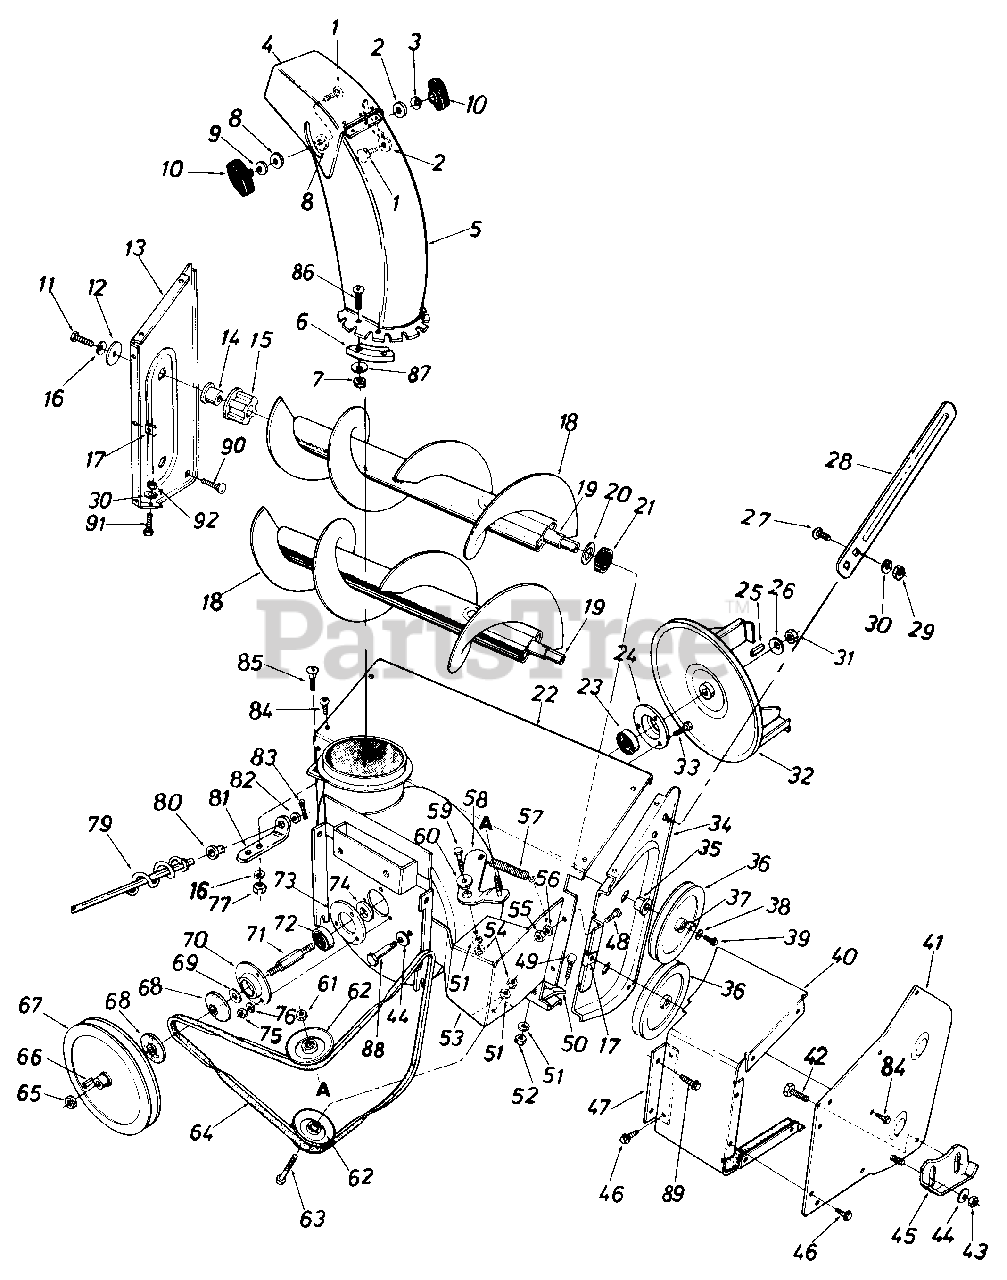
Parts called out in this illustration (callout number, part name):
1	Carriage Bolt 5/16-18 x 1.0" Lg.
2	Fl-Wash. .344" I.D. x 1.125 O.D.
3	Bell-Wash. .345" I.D. x .88" O.D.
4	Upper Chute
5	Lower Chute
6	Chute Flange Keeper
7	Hex Patch L-Nut 1/4-20 Thd.
8	Fl-Wash. .531' I.D. x 1.25" O.D.
9	Bell-Wash. .345" I.D. x .88" O.D.
10	Knob Handle Ass'y.
11	Hex Bolt 5/16-18 x 1.0" Lg. (Grade 5)
12	Fl-Wash. .32" I.D.
13	Spiral Housing Plate L.H.
14	Shaft Pin 1.0" O.D. x .94
15	Tubing Support Brg.
16	Bell-Wash. .345" I.D. x .88" O.D.
17	Speed Clip 1/4-20
18	Auger Ass'y. 22" x 6" Dia.
20	Fl-Wash. .760" I.D. x 1.75 O.D.
21	Spacer 1.25" I.D. x 1.50" O.D. x .58" Thk.
22	22" Spiral Housing Ass'y.
23	Ball-Brg. .787" I.D. x 1.85" O.D. x .551
24	Bearing Housing 1.85" I.D.
25	Sq. Key 3/16 x 1.50" Lg.
26	Bell-Wash. .630" I.D. x 1.25 O.D.
27	Carriage Bolt 5/16-18 x .62" Lg.
29	Hex Nut 5/16-18 Thd.
30	L-Wash. 5/16" I.D.
31	Hex Jam Nut 5/8-18 Thd.
32	11" Dia. Blower Fan Ass'y.
33	Hex Bolt 5/16-18 x 1.00" Lg. (Grade 5)
34	Spiral Housing Plate R.H.
35	Hex Flange Brg. .751 " I.D.
36	3/8" V-Pulley 5/8" I.D. x 5.5" O.D.
37	Sq. Key 3/16" X .75" Lg.
38	Bell-Wash. .265" I.D. x .75" O.D.
39	Hex Bolt 1/4-20 x .62" Lg.
40	Belt Cover Top
41	Belt Cover Side Ass'y.
42	Hex Bolt 3/8-16 x .75" Lg.
43	Hex Jam Nut 3/8-16 Thd.
44	Bell-Wash. .400" I.D. x .88" O.D.
47	Support Bracket
48	Hex Bolt 5/16-18 X .50" Lg.
49	Carriage Bolt 5/16-18 X .62" Lg.
50	Scraper Bar Kit 22"
51	Bell-Wash. .345" I.D. x .88" O.D.
52	Hex Nut 5/16-18 Thd.
54	Hex Nut 3/8-24 Thd.
55	Hex Nut 5/16-18 Thd.
56	L-Wash. 5/16" I.D.
57	Extension Spring .620" O.D. x 3" Lg.
58	Idler Bracket Ass'y.
59	Hex Bolt 3/8-24 x .75" Lg.
60	Shld. Spacer .625" I.D.
61	Hex Ins. L-Nut 3/8-24 Thd.
62	"V"-Idler 2.62" O.D.
63	Hex Bolt 3/8-24 x 1.25" Lg.
64	V-Belt
65	Hex Cent. L-Nut 5/8-18 Thd.
66	Sq. Key 3/16 x .75" Lg.
67	518" "V"-Pulley .628" I.D. x 7.50" O.D.
68	3/8" "V"-Pulley Half .625" I.D. x 2.25" O.D.
69	Fl-Wash. .635" I.D. x 1.0" O.D.
70	Open Brg. Housing Ass'y.
71	Fan Spindle
72	Ball Brg. .787" I.D. x 1.85" O.D.
73	Spindle Reinforcement Plate
74	Spacer .790" I.D. x 1.0" O.D.
75	Hex Nut 5/16-18 Thd.
76	L-Wash. 5/16" I.D.
77	Hex Nut 5/16-18 Thd.
79	Chute Crank Ass'y. R.H. 39.0" Lg.
80	Plastic Bushing 380" I.D.
82	Fl-Wash. .385" I.D. x .62" O.D.
83	Cotter Pin 8132" Dia. x :75" Lg.
84	Truss Mach. Scr. 1/4-20 x .501" Lg.
85	Carr. Bolt 5/16-18 X :75" Lg.
86	Truss Mach. Scr. 1/4-20 x .75"
87	Fl-Wash. .265" I.D. x .75" O.D. x .062
88	Shld. Bolt :5" Dia. x 2.11" Lg.
89	Hex Wash. Hd. Tap Scr. 5/16-24 x 5" Lg.
90	Carriage Bolt 3/8-16 x .62" Lg.
91	Hex Bolt 5/16-24 x .5" Lg.
92	Hex Nut 5/16-24 Thd.
05139A-0637	BLADE-GUIDE (DRIFT - POWDER BLACK (0637)
05139A-0638	BLADE-GUIDE (DRIFT - MTD/TROY-BILT RED (0638)
05139A-0662	BLADE-GUIDE (DRIFT - OYSTER GRAY (0662)
05139A-0665	BLADE-GUIDE (DRIFT - YARDMAN GREEN (0665)
05139A-0674	BLADE-GUIDE (DRIFT - YARDMAN YELLOW (0674)
05139A-0716	BLADE-GUIDE (DRIFT - CUB YELLOW-99 (0716)
